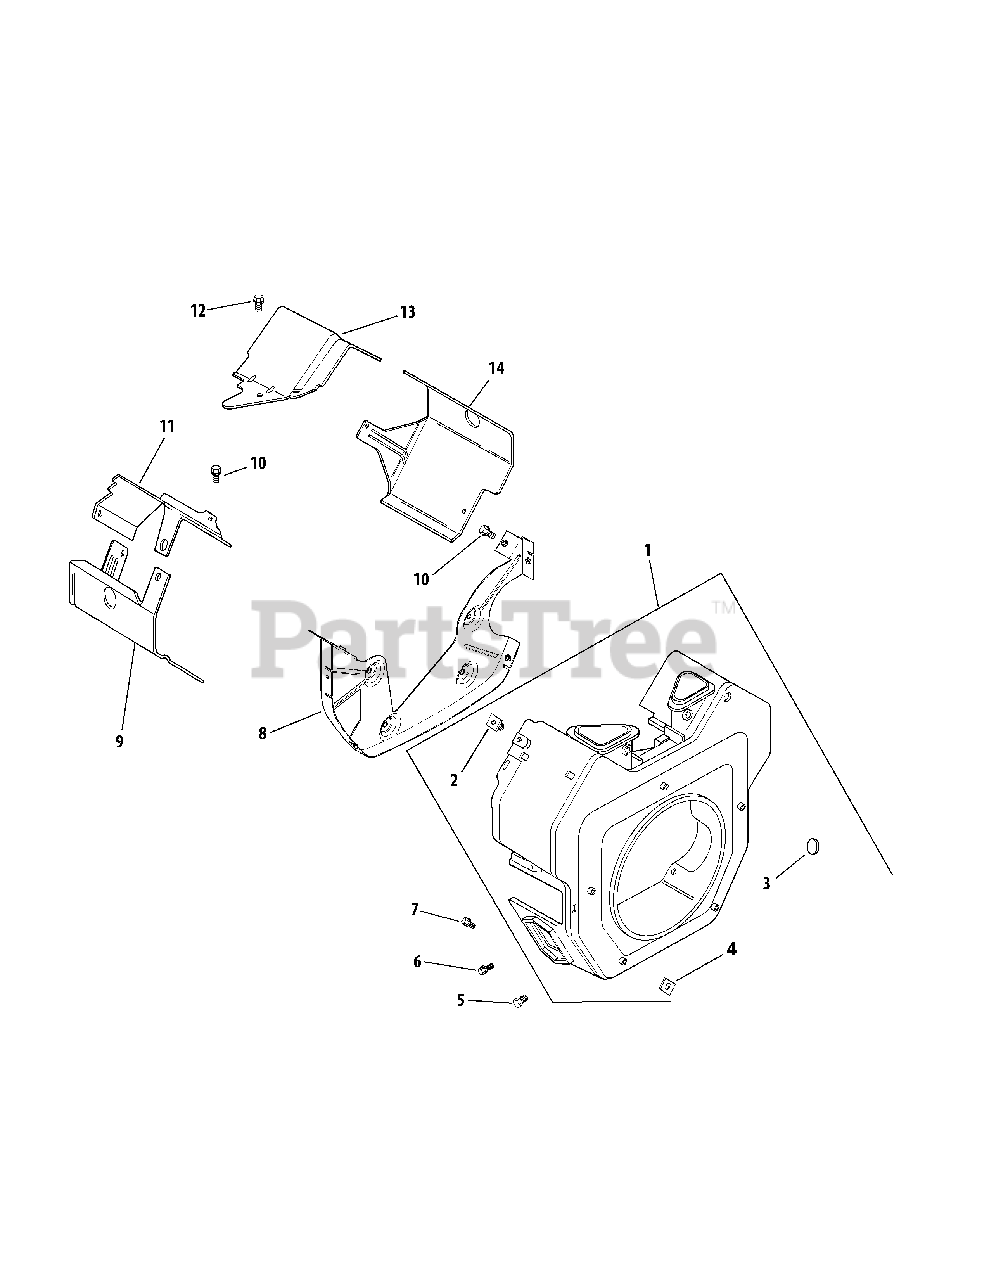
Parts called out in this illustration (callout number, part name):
1	Housing, Blower (Incl. Ref #2-4)
3	Plug, Button, 9/16
4	Nut, Plastic
5	Screw, Hex Flange, M5 x 0.8 x 16
6	Screw, Hex Flange, M5 x 0.8 x 16
7	Screw, Hex Flange, M5 x 0.8 x 20
8	Plate, Backing
9	Baffle, Cylinder Barrel - #2 Side
10	Screw, Hex Flange, M6 x 1.0 x 16
11	Baffle, Valley - #2 Side
12	Screw, Hex Flange, M5 x 0.8 x 10
13	Baffle, Valley - #1 Side
14	Baffle, Cylinder Barrel - #1 Side
